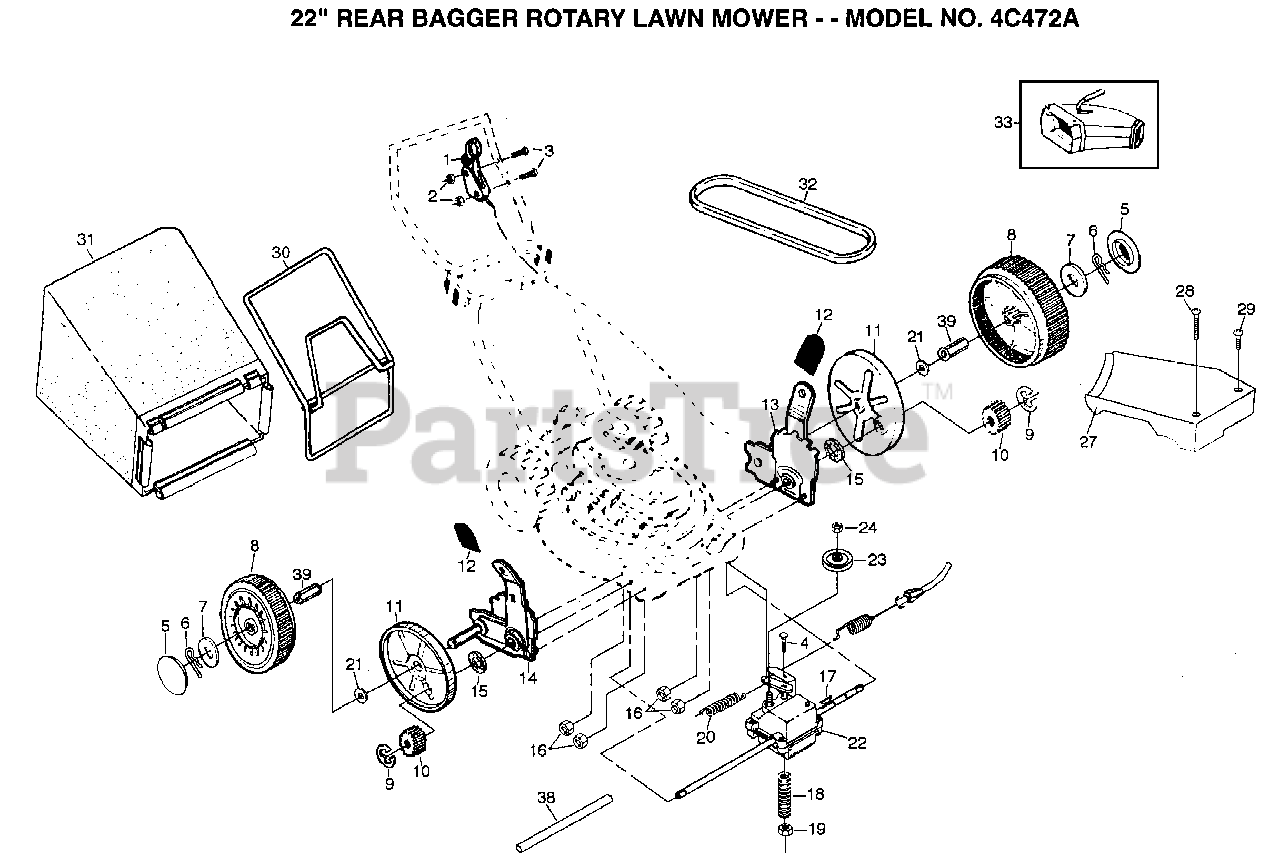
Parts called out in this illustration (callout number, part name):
1	CONTROL.DRIVE
3	SCREW
4	BOLT.1/4-20X2.0
5	HUB CAP
6	RETAINER CLIP PM
7	WASHER
8	WHEEL.8X2.LP.PR
10	PINION.GEAR
11	DUST SHROUD PM
12	KNOB PM
15	WASHER PM
17	HI PRO KEY
18	SPRING.TENSION
20	SPRING.RETURN
21	WASHER FLUT
23	PULLEY.DRIVEN
24	LOCKNUT
27	"COVER.DRIVE 22""RD"
30	CATCHER FRAME
31	GRASS BAG
38	DRV SHAFT TUBE PM
39	BUSHING.HEX
